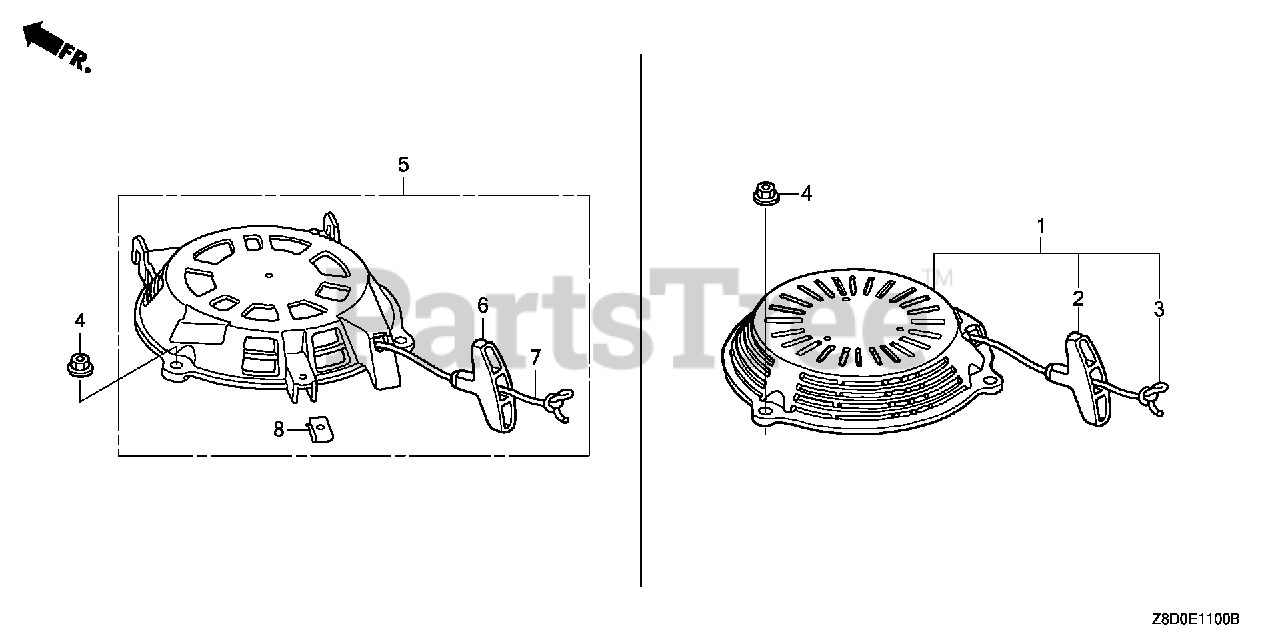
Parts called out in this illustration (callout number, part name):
1	STARTER ASSY., RECOIL *R280* (SHORT ROPE) (POWER RED)
2	GRIP, STARTER
3	ROPE, RECOIL STARTER
4	NUT, FLANGE (6MM)
